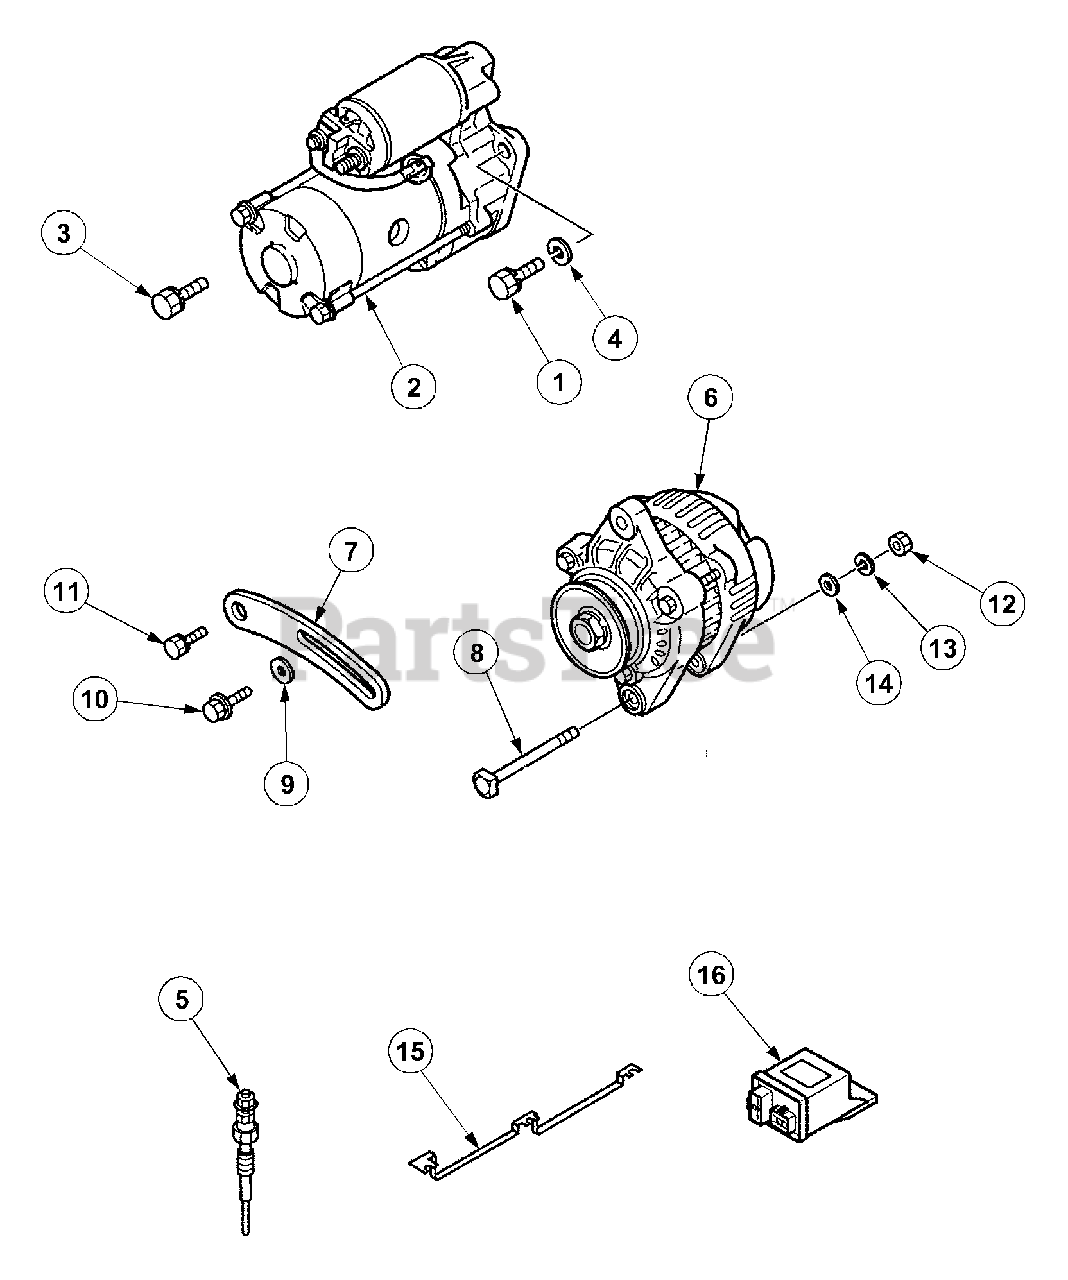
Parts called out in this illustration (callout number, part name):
1	Bolt,Starter
3	Bolt,w/Washer
4	Washer,Spring
6	Alternator Ass'y.
7	Plate,Adjusting
8	Bolt,Alternator
10	Bolt,Flange
11	Bolt,w/Washer
13	Washer,Spring
14	Washer,Plain
15	Plate,Connect
16	Controller,Glow
